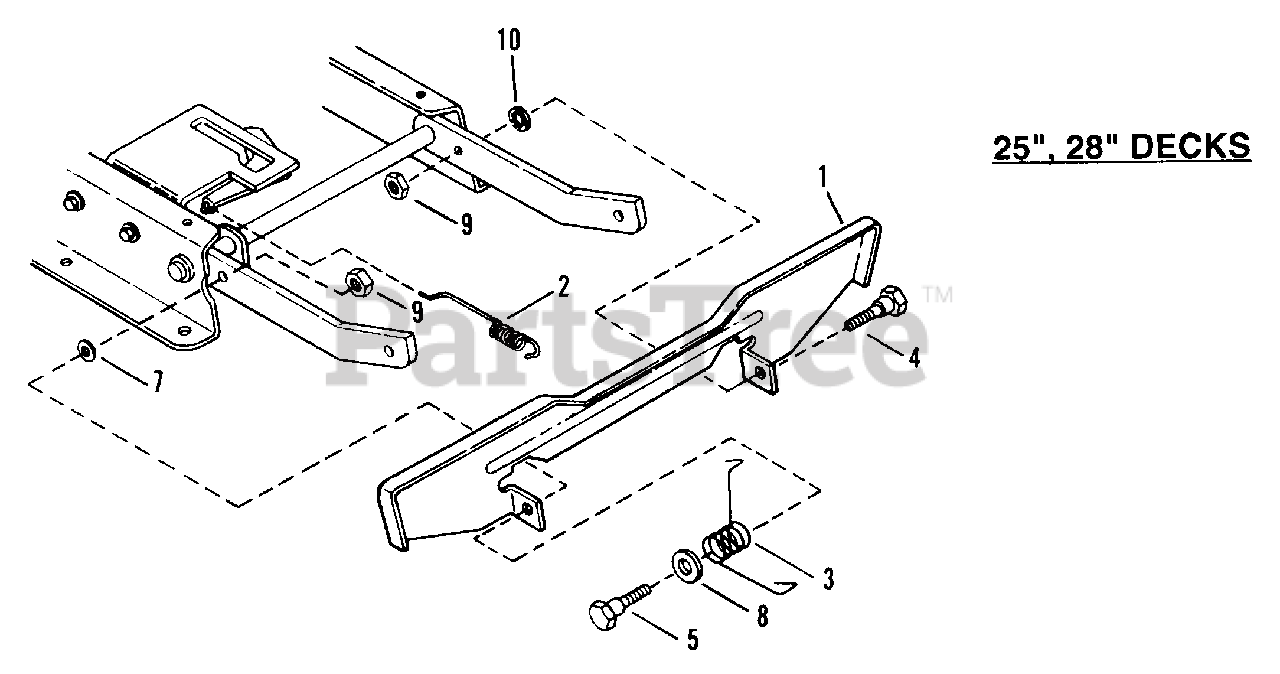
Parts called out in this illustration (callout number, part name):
1	PEDAL, Blade Stop Control
2	SPRING, Latching
3	SPRING, Pedal
4	BOLT, 3/8-24 x 3/4" Shoulder
5	BOLT, 3/8-24 x 9/16" Shoulder
7	WASHER, 3/8" Flat
8	WASHER, 1/2 Flat
9	NUT, 3/8-24 Hex Lock
10	WASHER, 3/8 Internal Tooth Lock
